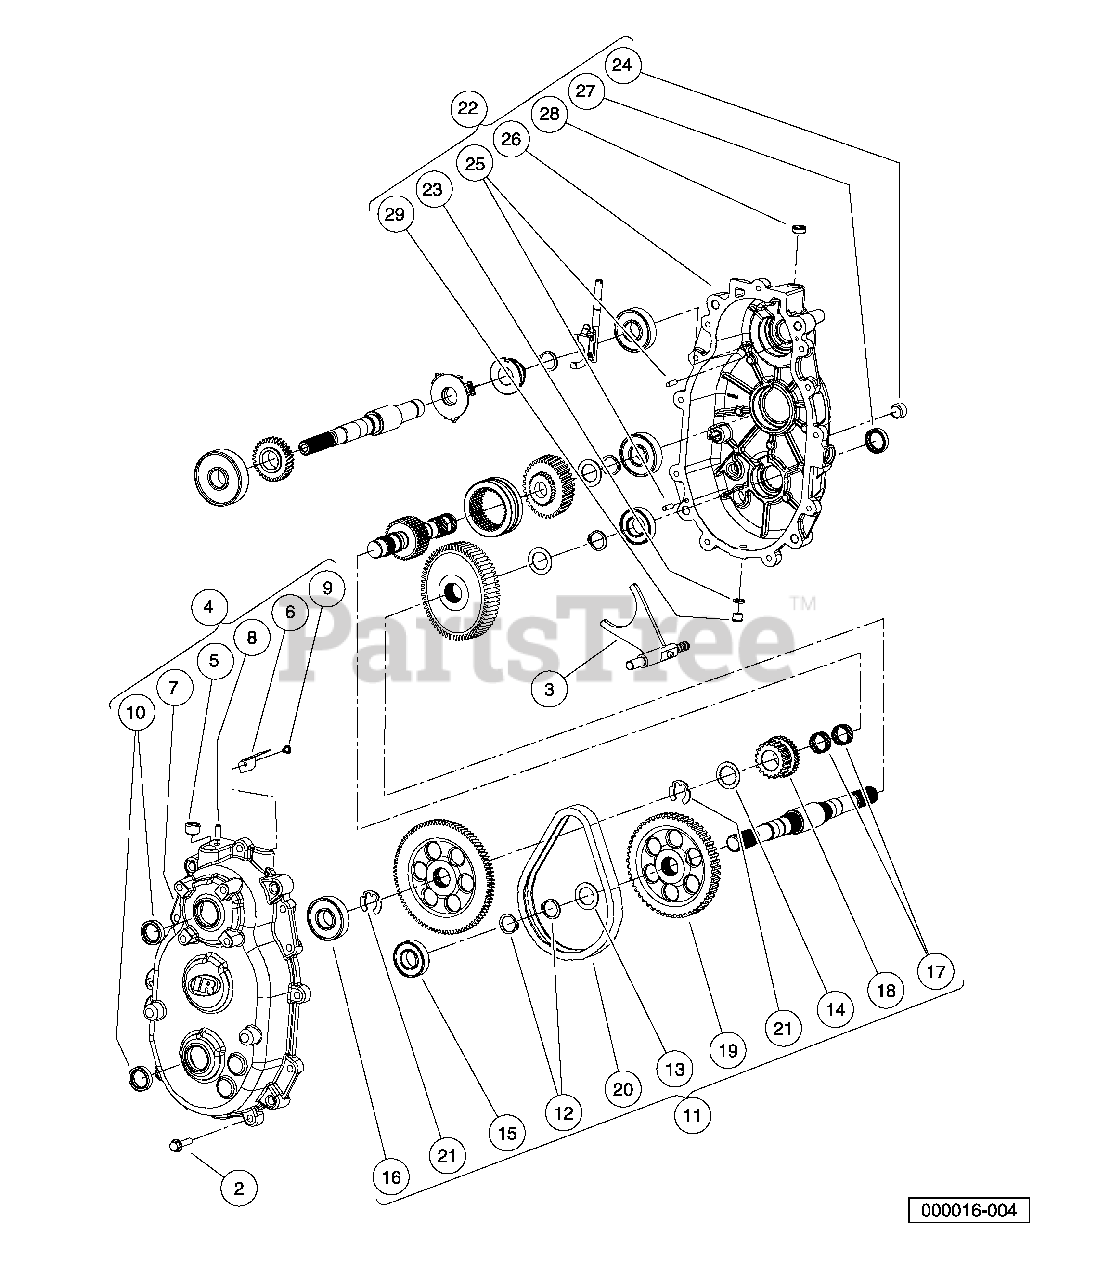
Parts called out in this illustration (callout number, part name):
1	Transmission, Parallel Shaft
2	Screw,hex Flange, M8 X 35
3	Fork, Transmission
4	Asm, Gear Case, Rear
5	Plug, Square Skt, 1/12-14, Ptf
6	Oil, Deflector
7	Gearcase, Rear
8	Vent, Trans
9	Screw, Tapping # 10-24 X .375
10	Seal, Triple, 25 X 35 X 7.8
11	Kit, Reverse Gear Repair
12	Ring, Retaining, Basic External
13	Washer, Thrust, 1.007 X .062
14	Washer, 26.231 X 39.167 X 1.57
15	Bearing, Ball.
16	Bearing, Ball.
17	Bearing, Needle
21	Ring, Retaining, E-Ring
22	Asm, Case, Gear, Front
23	Washer, .625 X .382 X .60
24	Plug, Square Skt, 1/12-14, Ptf
25	Pin, Dowel, 6 X 20
26	Gearcase, Front
27	Seal, Triple, 25 X 35 X 7.8
28	Seal, Dual-Lip
29	Plug, 3/4-16
